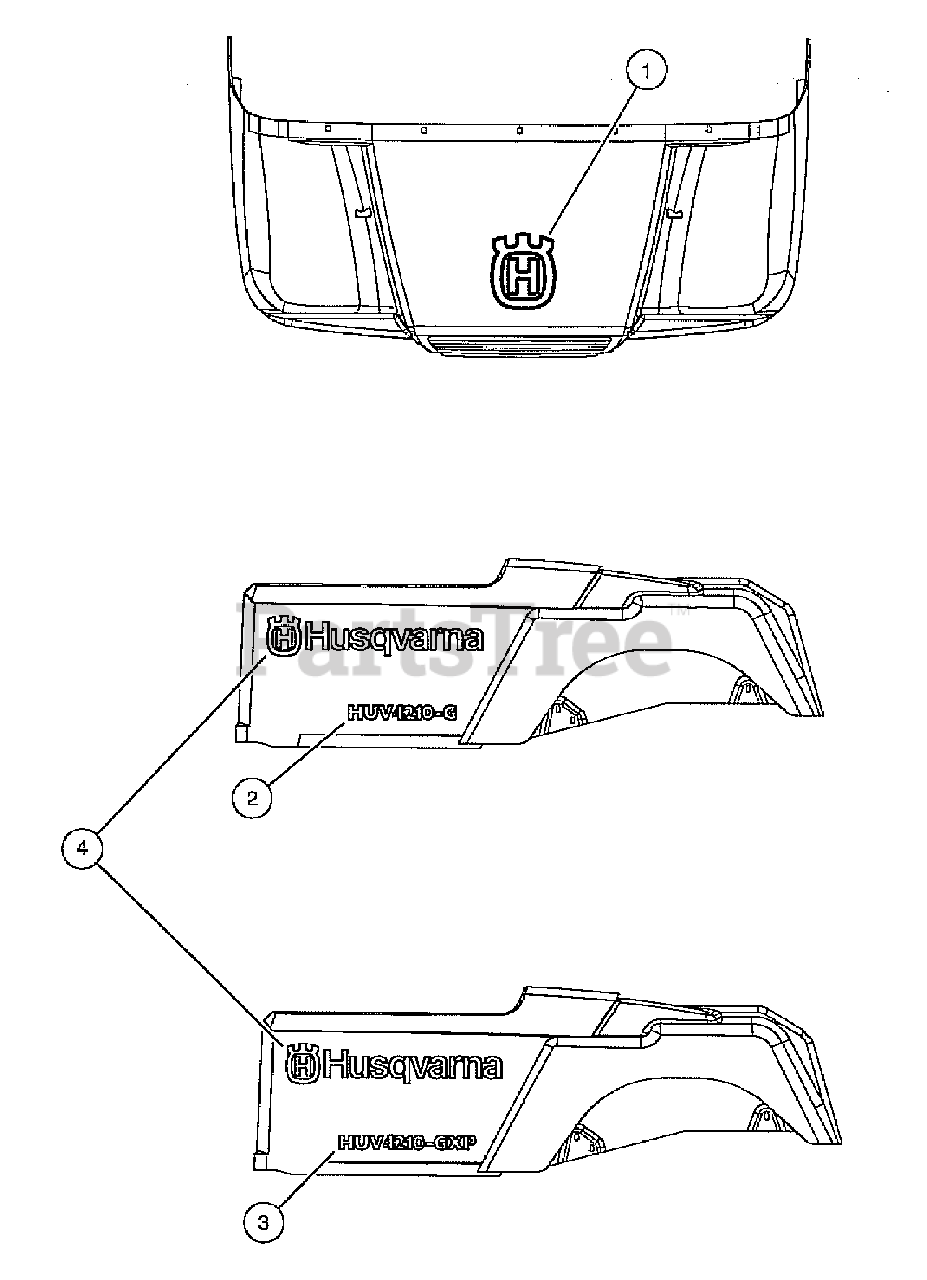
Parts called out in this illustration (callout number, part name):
1	Decal, Husqvarna, Cowl
2	Decal, Husqvarna, Side Panel (HUV4210-G)
3	Decal, Husqvarna, Side Panel (HUV4210-GXP)
4	Decal. Husq, Side
